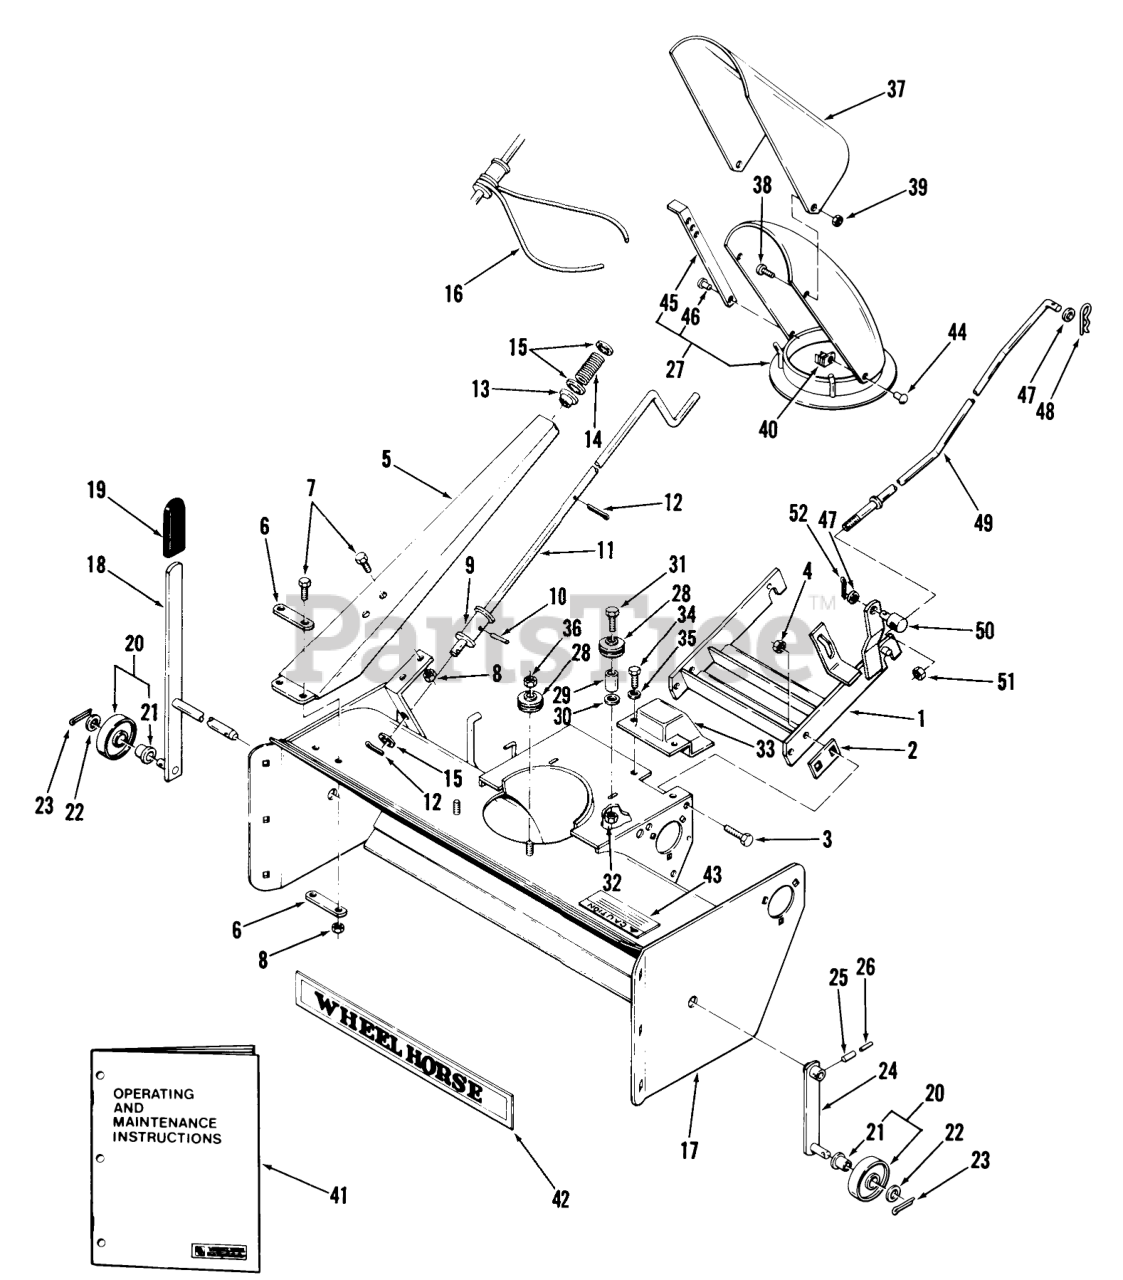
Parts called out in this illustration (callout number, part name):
1	Mounting Frame
2	STRAP
3	Bolt
4	NUT
5	Crank Support
6	Bar-Reinforcing
7	Bolt
8	Nut
9	ASSY TUBE CRANK R
10	ROLL PIN 1/4 X 1-1/4
11	Crank
12	Pop Rivet
13	NYLINER BUSHING
14	SPRING-COMPRESSION
15	Washer
16	CABLE
17	X APPER ASSY
18	ASSY AUGER SHAFT R
19	GRIP
20	Wheel Assembly (Includes Item 21)
21	Bushing
22	Washer
23	Pop Rivet
24	Wheel Support
25	ROLL PIN 1/4 X 1-1/4
26	PIN-SPIROL
27	Shroud Assembly (Includes Item 45 & 46)
28	Roller
29	SPACER
31	Bolt
32	Nut
33	COVER-BELT
34	Bolt
36	NUT
37	Deflector
38	MACH. SCREW
39	Nut
40	CLAMP
41	Operating and Maintenance Instructions
42	DECAL-WHEEL HORSE
43	Decal-Caution
44	RIVET-4
45	ARM R
46	RIVET
47	Washer
48	Hairpin Cotter
50	TRUNION
51	Nut
